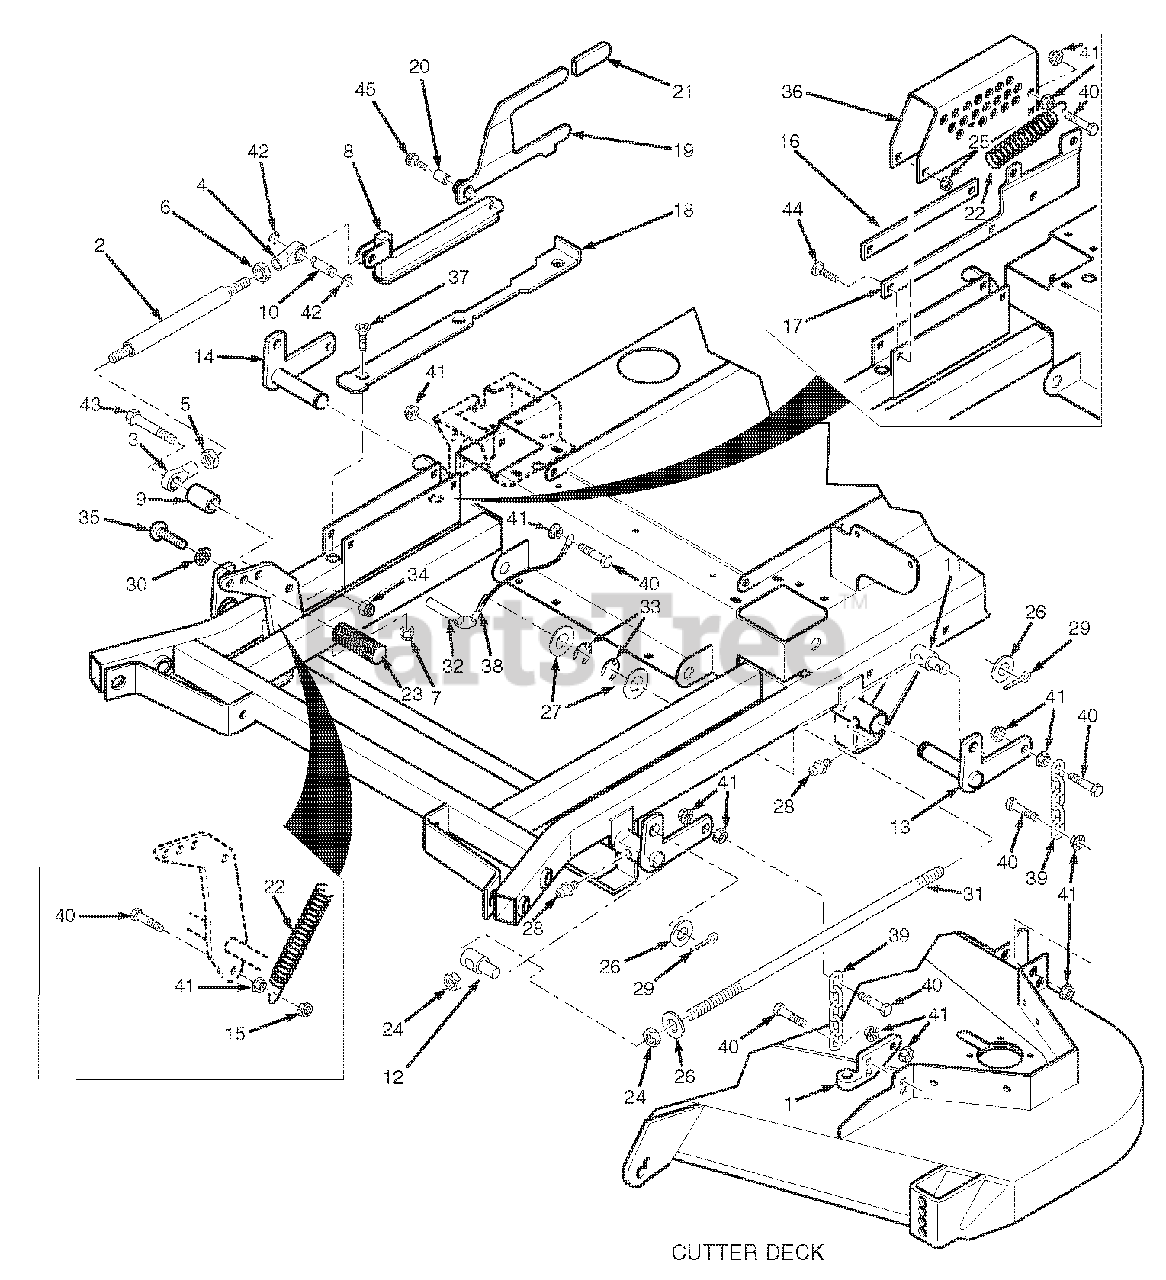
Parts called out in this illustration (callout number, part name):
1	Lever Assembly, Deck Level
2	Link, Deck Lift
3	Rod End, Female - 1/2-20 RH
4	Rod End, Female - 1/2-20 LH
5	Nut, Jam 1/2-20 RH
6	Nut, Jam 1/2-20 LH
7	Nut, 3/8-16 Elastic Stop
8	Slide Weldment, Height Adjustment
9	Spacer, Decklift Pedal
10	Pin, Decklift
11	Swivel Joint, LH
12	Swivel Joint, RH
13	Bellcrank Weldment, LH Rear
14	Bellcrank Weldment, RH Rear
15	Locknut, 3/8-16 Center Lock
16	Guide, Short
17	Guide, Long
18	Lockplate, Decklift
19	Deck Latch
20	Bushing, .502" I.D.
21	Grip, Deck Latch
22	Spring, Helper (61" & 72" Cutter Decks Only)
23	Foot Pedal, Height Adjustment
24	Nut, Hex 5/8-11
25	Nut, Hex Serr. Flng. 5/16-18
26	Flatwasher, 5/8" (.656 x 1.312 x .095")
27	Flatwasher, 1" (1.062 x 1.50 x .048")
28	Grease Fitting
29	Cotter Pin, 3/16 x 1"
30	Lockwasher, 5/8"
31	Stud, 5/8-11 x 22.0"
32	Ring Pin, 1/2 x 3.06"
33	Ring, Retaining 1" External "E"
34	Nut, Hex Elastic Stop 1/2-13
35	Capscrew, 5/8-11 x 1-1/2"
36	Bracket, Cutting Height Adjustment
37	Screw, Cap 5/16-18 x 3" FHHS
38	Lanyard, Deck Height Pin
39	Chain
40	Bolt, Hex Hd. 3/8-16 x 1-1/2"
41	Nut, Hex Serr. Flng. 3/8-16
42	Ring, Retaining 1/2" External "E"
43	Bolt, Hex Hd. 1/2-13 x 3"
44	Bolt, Carriage 5/16-18 x 1"
45	Bolt, Shoulder 1/2 x 3/4"
